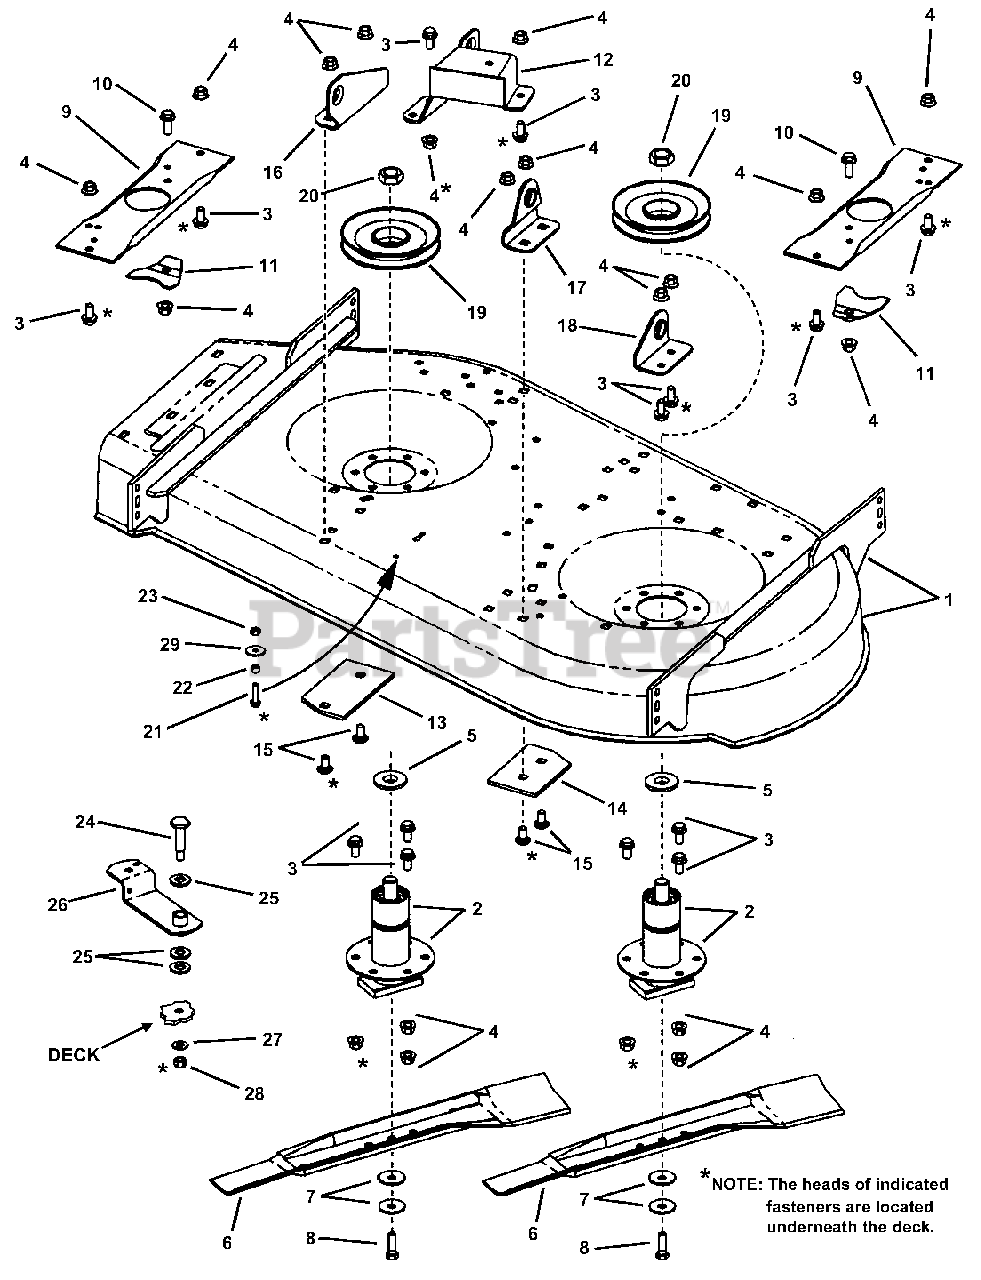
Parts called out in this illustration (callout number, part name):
1	DECK, Painted Shell w/Decals
2	ASSEMBLY, Spindle Brake
3	BOLT, 3/8-16 x 3/4" Hex Flange Lock, Grade 5
4	NUT, 3/8-16 Hex Fl. Lock
5	WASHER, Spindle
6	BLADE, 21" Standard Lift
7	WASHER, Cone
8	SCREW, 3/8-24 x 1-1/4" Hex Head Cap, Grade 5
9	BRACE, Spindle
10	BOLT, 3/8-16 x 1" Hex Flange Lock
11	ASSEMBLY, Spindle Lock
12	IDLER, Stationary
13	REINFORCEMENT, R.H.
14	REINFORCEMENT, L.H.
15	BOLT, 3/8-16 x 3/4" Short Neck Carriage, Grade 5
16	BRACKET, R.H. Front Lift
17	BRACKET, L.H. Front Lift
18	BRACKET, L.H. Rear Lift
19	PULLEY, 5-1/4"
20	NUT, 3/4-16 Hex Flange Jam, Grade 8
21	BOLT, 1/4-20 x 1-1/8, Grade 5
22	SPACER, .26 x .3
23	NUT, 1/4-20 Hex Center Lock
24	SHOULDER BOLT, 3/8-24 x 5/8"
25	WASHER, 1/2" I.D. x 1-1/16" O.D. Flat
26	IDLER ARM
27	WASHER, 3/8" Flat
28	NUT, 3/8-24 Hex Center Lock
29	WASHER, 1/4" Flat
